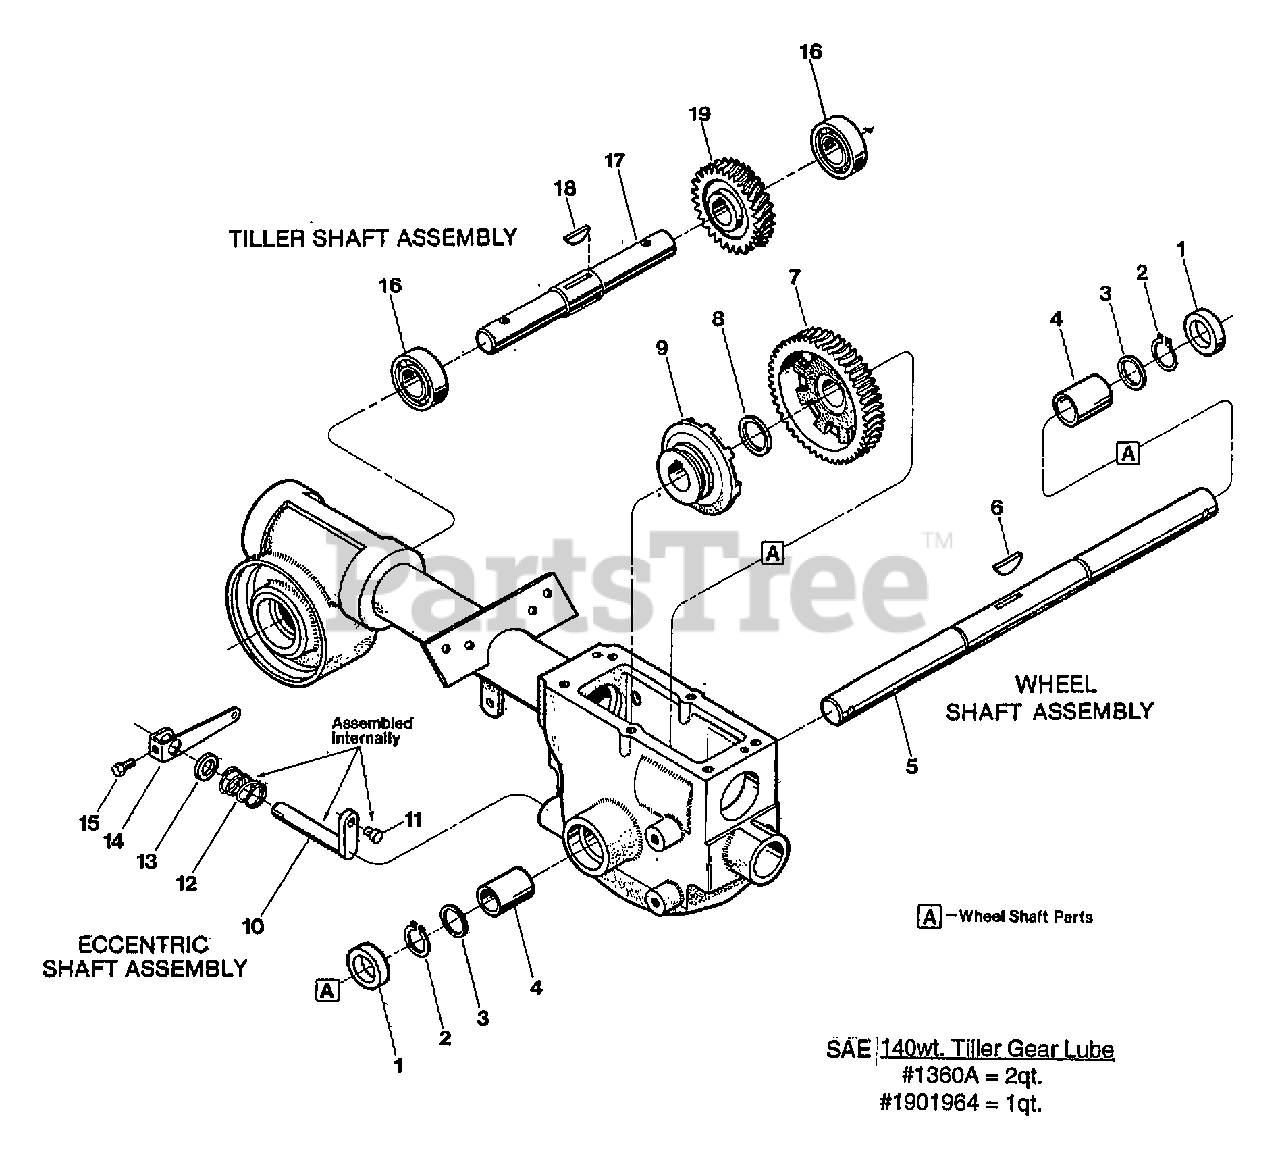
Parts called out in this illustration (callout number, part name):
1	SEAL-OIL WHEELSHAFT - LEFT AND RIGHT SIDES
2	RING-HEAVY EXT .906 ID
3	SHIM-1.375X1.015X.062
3	SHIM-1.375X1.015X.03
3	SHIM-1.375X1.015X.015
3	SHIM-1.375X1.015X.01
4	BUSHING-1.25X1.005X1.5
5	ASSM-WHEEL SHAFT W/KEY
6	KEY-HI PRO .25X1.312
7	GEAR-WORM 46 TEETH MACH
7	GEAR-WHEEL DRIVE MACH
8	WASHER-1.468X1.016X.062
9	CLUTCH-MACH
10	WELD-ECCENTRIC
11	PIN-.375 X .72
12	SPRING-.850 X .875 LONG
13	SEAL-OIL ECCENTRIC
14	LEVER-CABLE ADJ PNT
15	SCR-HH 1/4-20X.5 GR5 YEL
16	BEARING-BALL
17	SHAFT-W/KEY (TILLER)
18	KEY-WOODRUFF .25X1.12
19	GEAR-TILLER MACH
